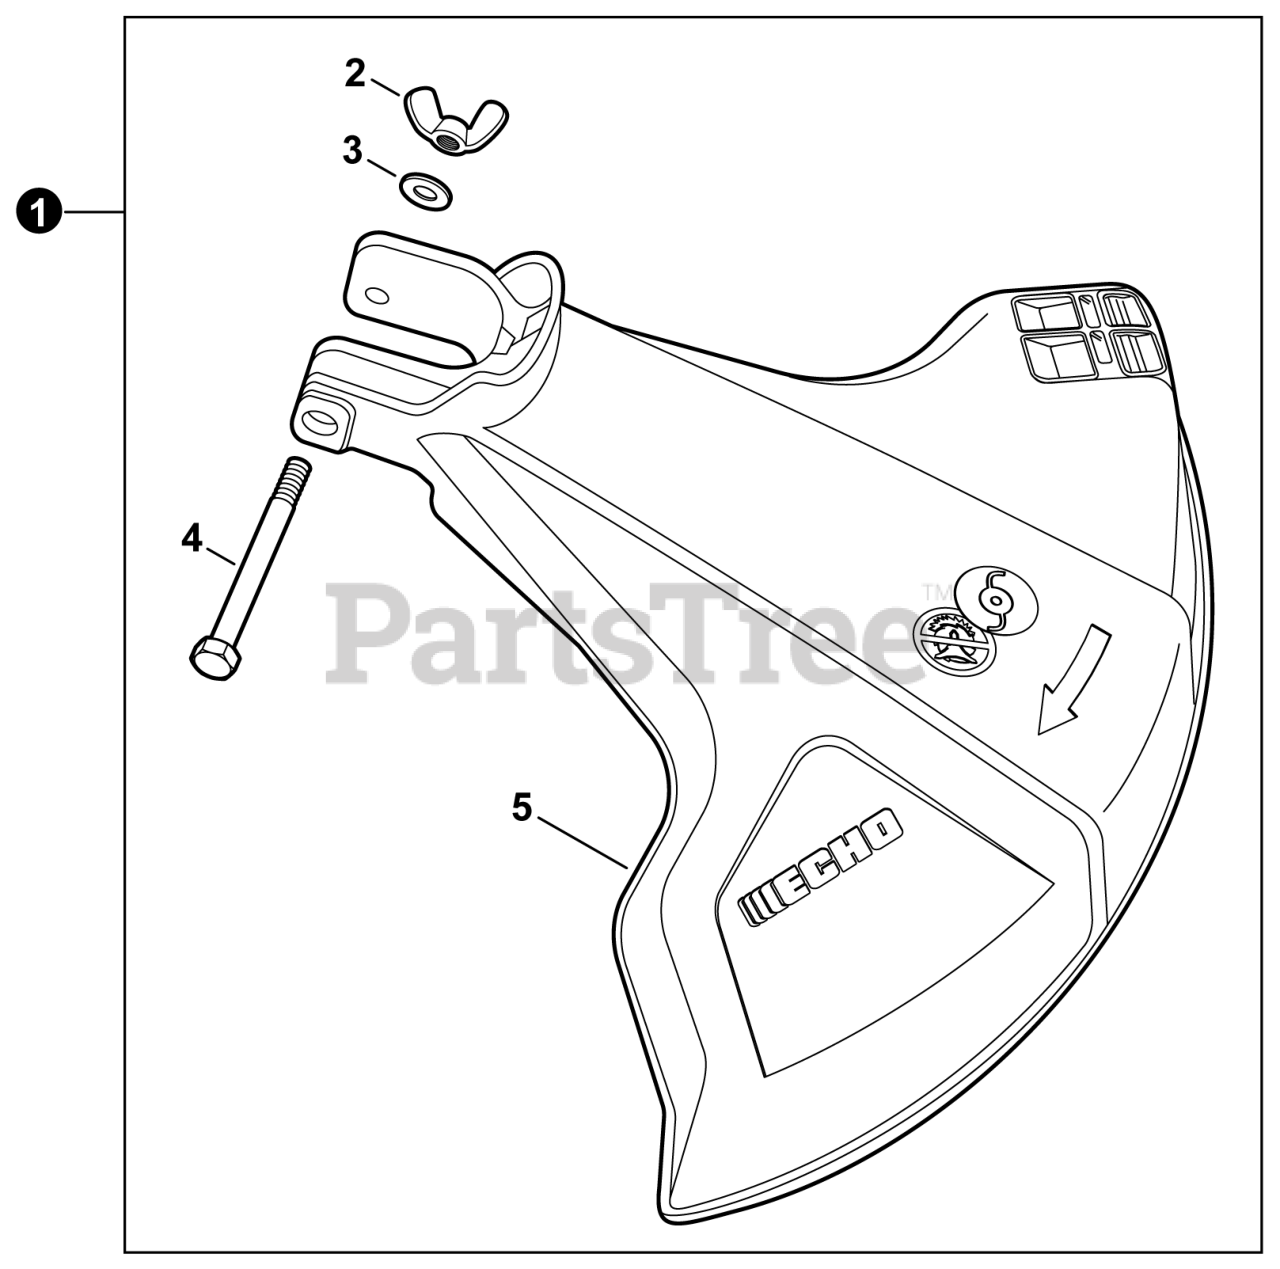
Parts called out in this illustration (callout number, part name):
1	SHIELD ASSY, DEBRIS
2	NUT, WING 1/4"-20
3	WASHER, 1/4"
4	BOLT 1/4"-20x2"
5	SHIELD, DEBRIS
